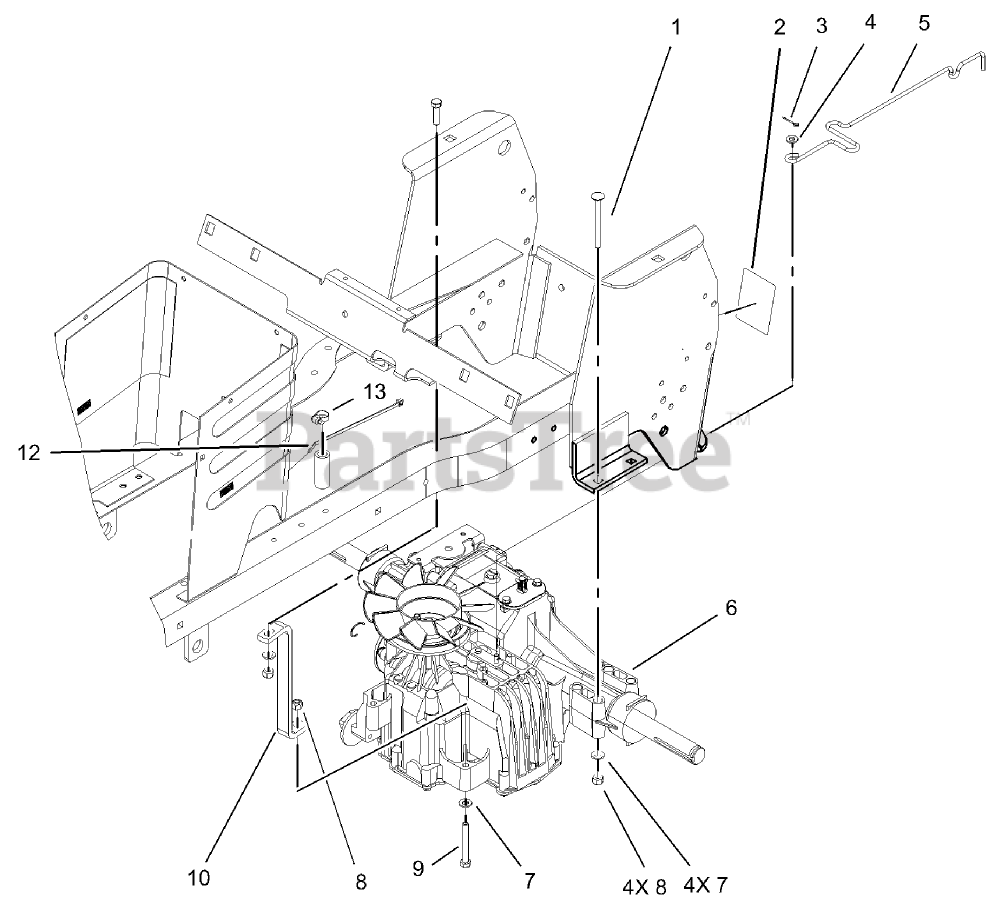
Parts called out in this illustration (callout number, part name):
1	BOLT-CARR
2	DECAL-VALVE, HYDRO
3	PIN-COTTER
4	WASHER-FLAT
5	ROD-BYPASS
6	TRANSAXLE-HYDROSTATIC
7	WASHER-PLAIN
8	NUT-LOCK, NI
9	SCREW-HH
12	TIE-CABLE
13	CLAMP-HOSE, WORM DRIVE
